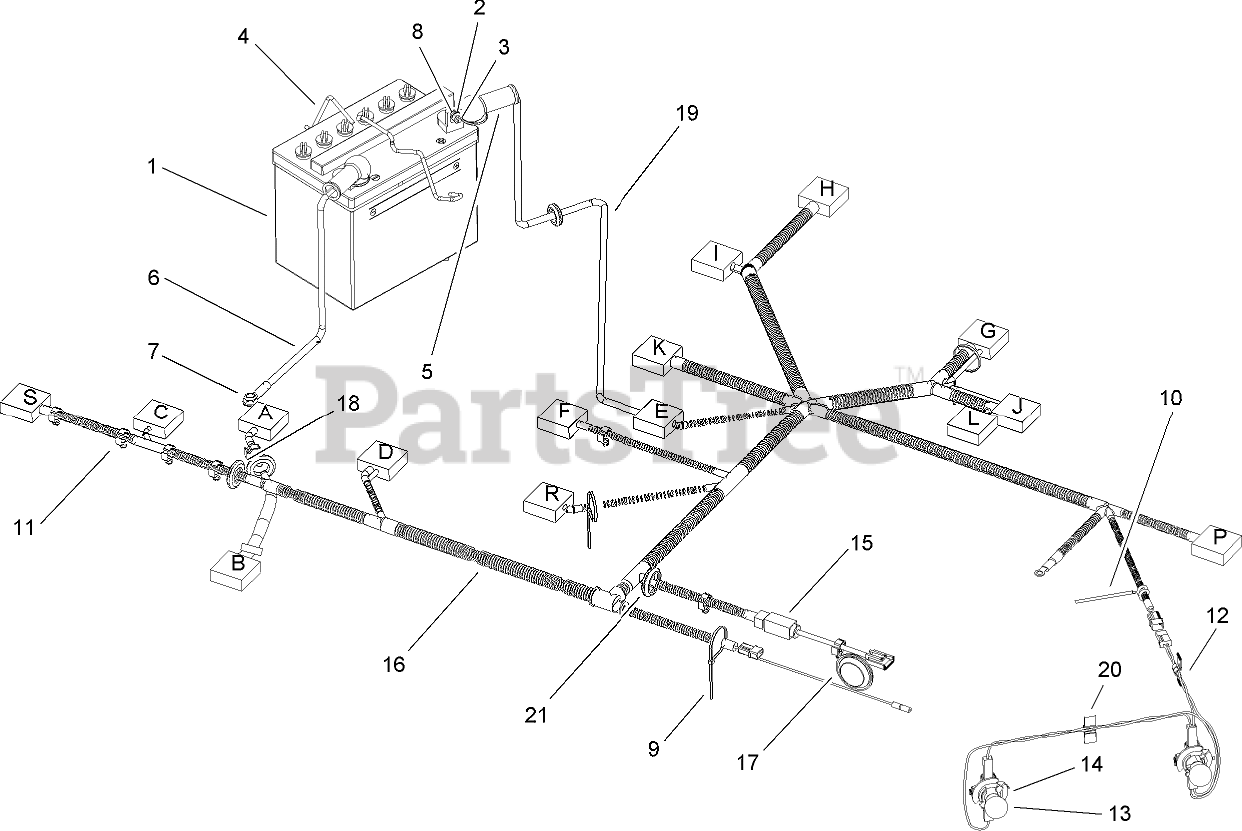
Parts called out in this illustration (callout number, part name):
1	BATTERY
2	NUT-HEX
3	SCREW-HH
4	CLAMP-BATTERY
5	BOOT-RUBBER
6	CABLE-BATTERY, NEGATIVE
7	NUT-LOCK, NI
8	WASHER-FLAT
9	TIE-CABLE
10	HOLDER-HARNESS, WIRING
11	CLIP-SNAP
12	HARNESS-WIRE, LIGHTS
13	BULB-LIGHT
14	SOCKET-LIGHT
15	HARNESS-CLUTCH
16	HARNESS-WIRING
18	BUSHING
19	CABLE-BATTERY, POSITIVE
20	CLIP-NYLON
21	BUSHING
